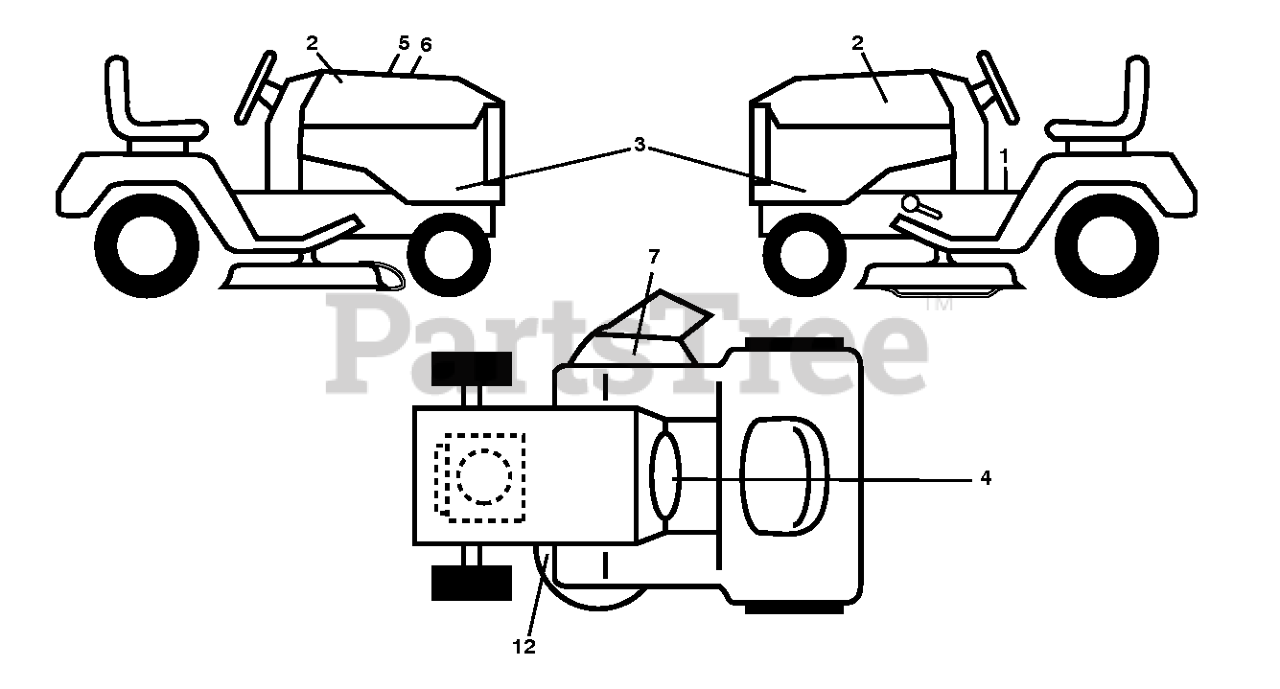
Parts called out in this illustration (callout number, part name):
1	DECAL.FENDER.WARNING.ENGLISH
2	DECAL.WB.178MM.15.HUSQ.NEWBRAN
3	DECAL.SDPNL.YTH20K46.SET
4	DECAL, WARNING SPARK ARRESTOR
5	DECALS.WARN.CA.SPKARREST/PROP
6	DECAL.RPL.KH.KT7.TLW.46.K46AL
7	DECAL, DECK DEFLECTOR, WARNING
12	DECAL.V-BELT.SCH.42/46"MEC/ELE
